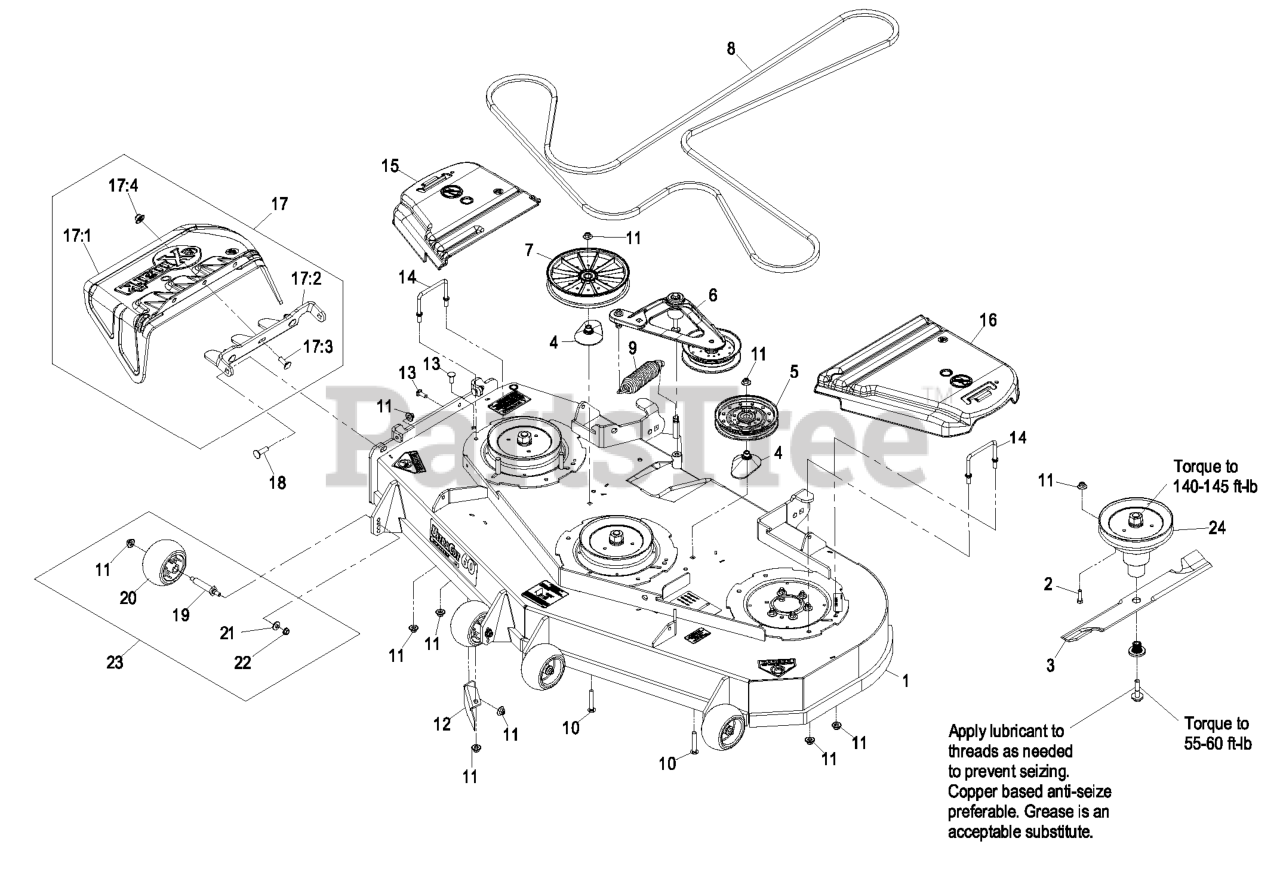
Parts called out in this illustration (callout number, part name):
1	DECK W/ DECALS ASM-604
2	SCREW-HH
4	SPACER-PULLEY
7	PULLEY,IDLER 8"FLAT
8	BELT,V-5V-198.75
10	SCREW-CARR
11	Nut-Nyloc 3/8-16 Flg
12	BAFFLE,DISCHARGE 52/60
13	SCREW-CARR
14	WIREFORM-COVER
15	COVER-BELT, RH
16	COVER-BELT, LH
17	ASM,DISCHARGE CHUTE
17:1	CHUTE,DISCHARGE
17:2	BRACKET,DISCHARGE CHUTE
17:3	SCREW-CARR
17:4	Nut-Nyloc 3/8-16 Flg
18	Bolt-Carriage 3/8-16 X 1 1/4
20	ROLLER-SCALP, ANTI
21	WASHER-BELLEVILLE
22	NUT-HHF, WHIZ
24	KIT,CUTTER HOUSING 60
25	Asm, Deck Complete 604
